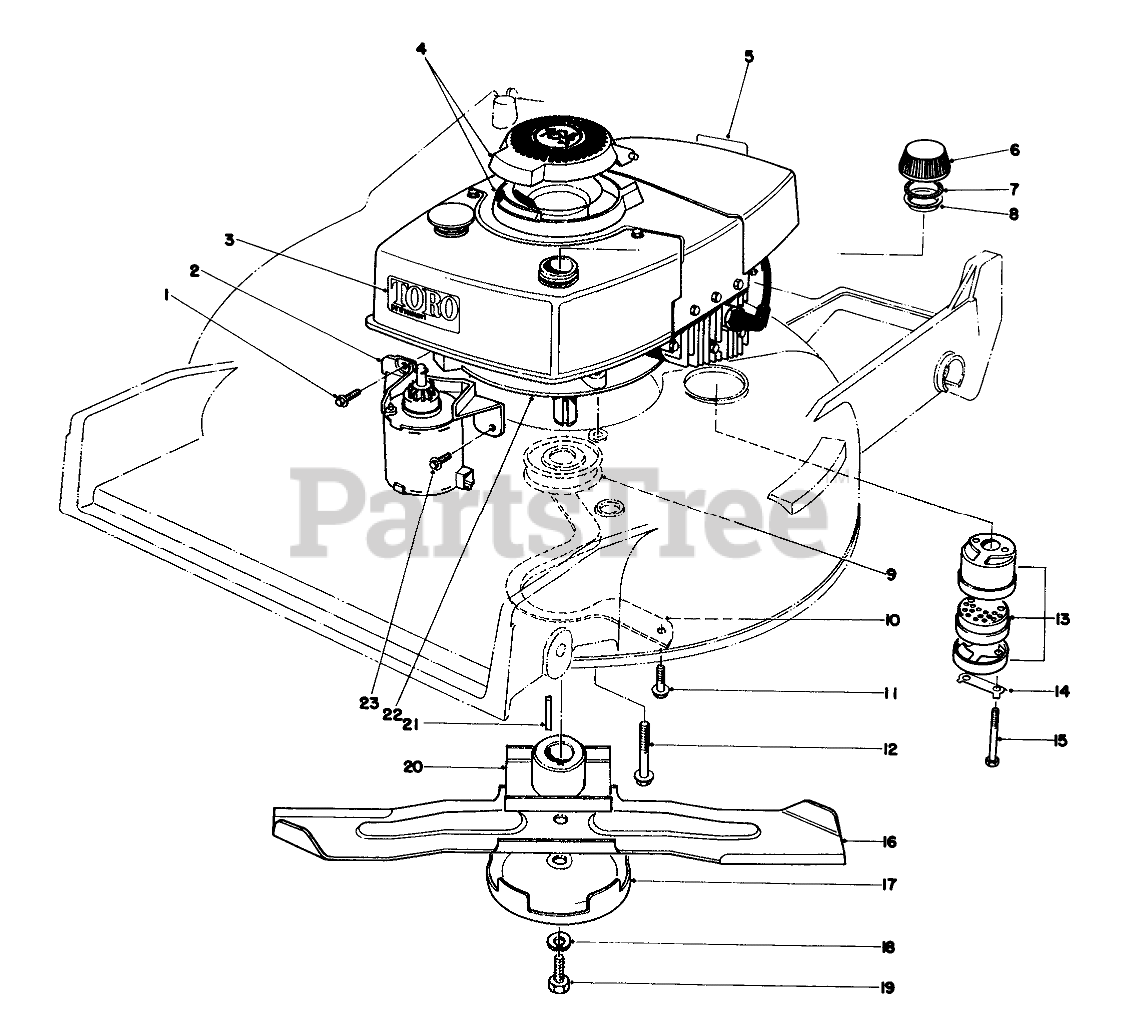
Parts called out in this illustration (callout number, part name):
1	Screw
2	Starter Motor
3	Decal
4	Cover
5	Decal-Maintenan
6	Gas Cap (Incl. Ref. #7 & 8)
7	GASKET
8	GAS CAP BAFFLE
9	DRIVER PULLEY
10	BELT GUIDE
11	Screw
12	SCREW-HWHTF
13	Muffler Assembly (Incl. Ref. 14 & 15)
14	CLIP - LOCKING
15	SCREW-HH
16	Blade
17	AntiScalp Cup
18	WASHER-LOCK
19	BLADE SCREW
20	BLADE RETAINER WA(BLACK)
21	KEY-SQUARE
22	Engine
23	SCREW
